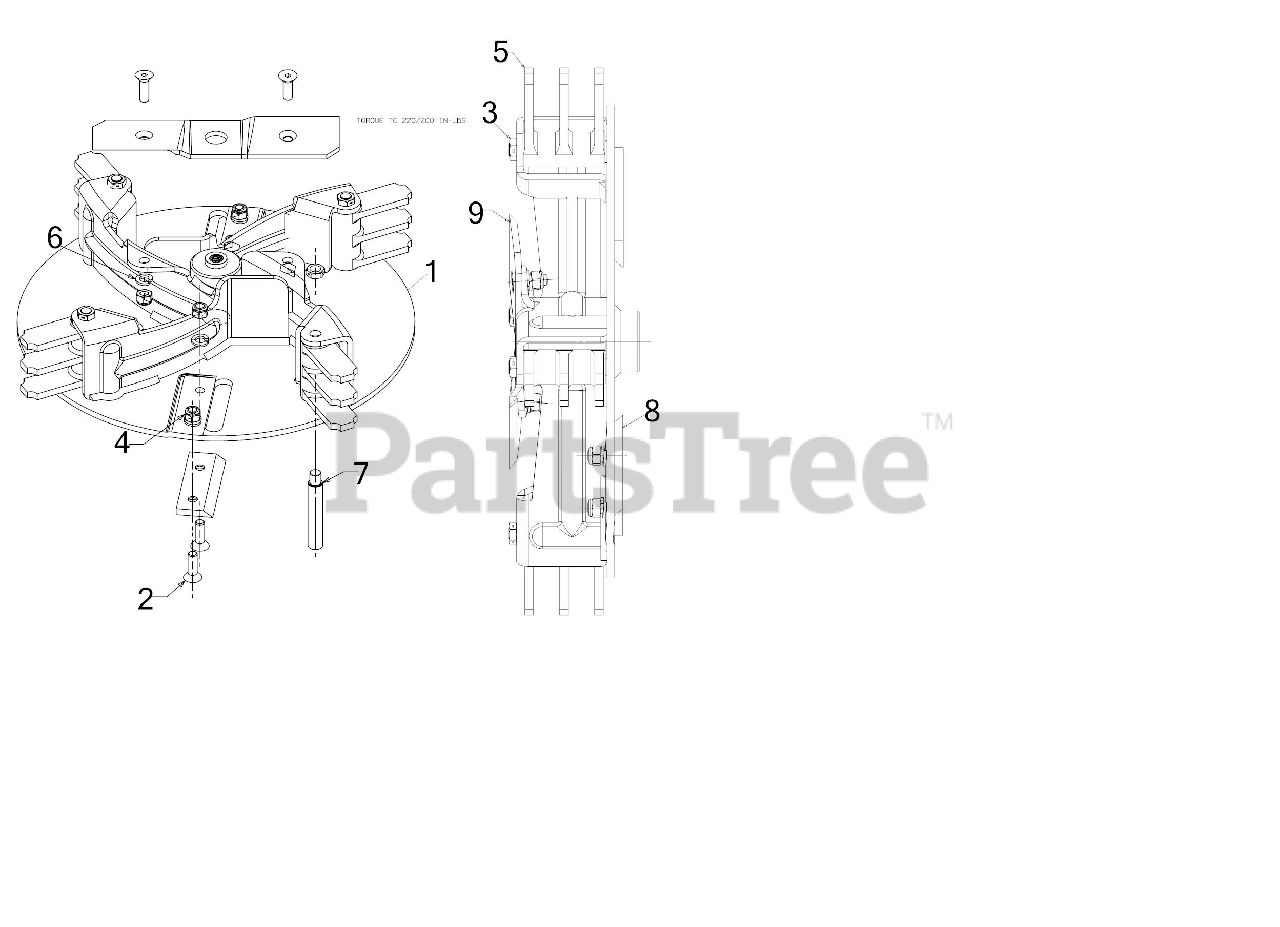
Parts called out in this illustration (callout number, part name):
1	IMPELLER WELDMENT
2	SCREW 5/16-24 x 1
3	JAM LOCK NUT
4	HEX NUT
5	FLAIL BLADE
6	LOCK WASHER 5/16
7	SHOULDER PIN
8	CHIPPER BLADE
9	SHREDDER BLADE
